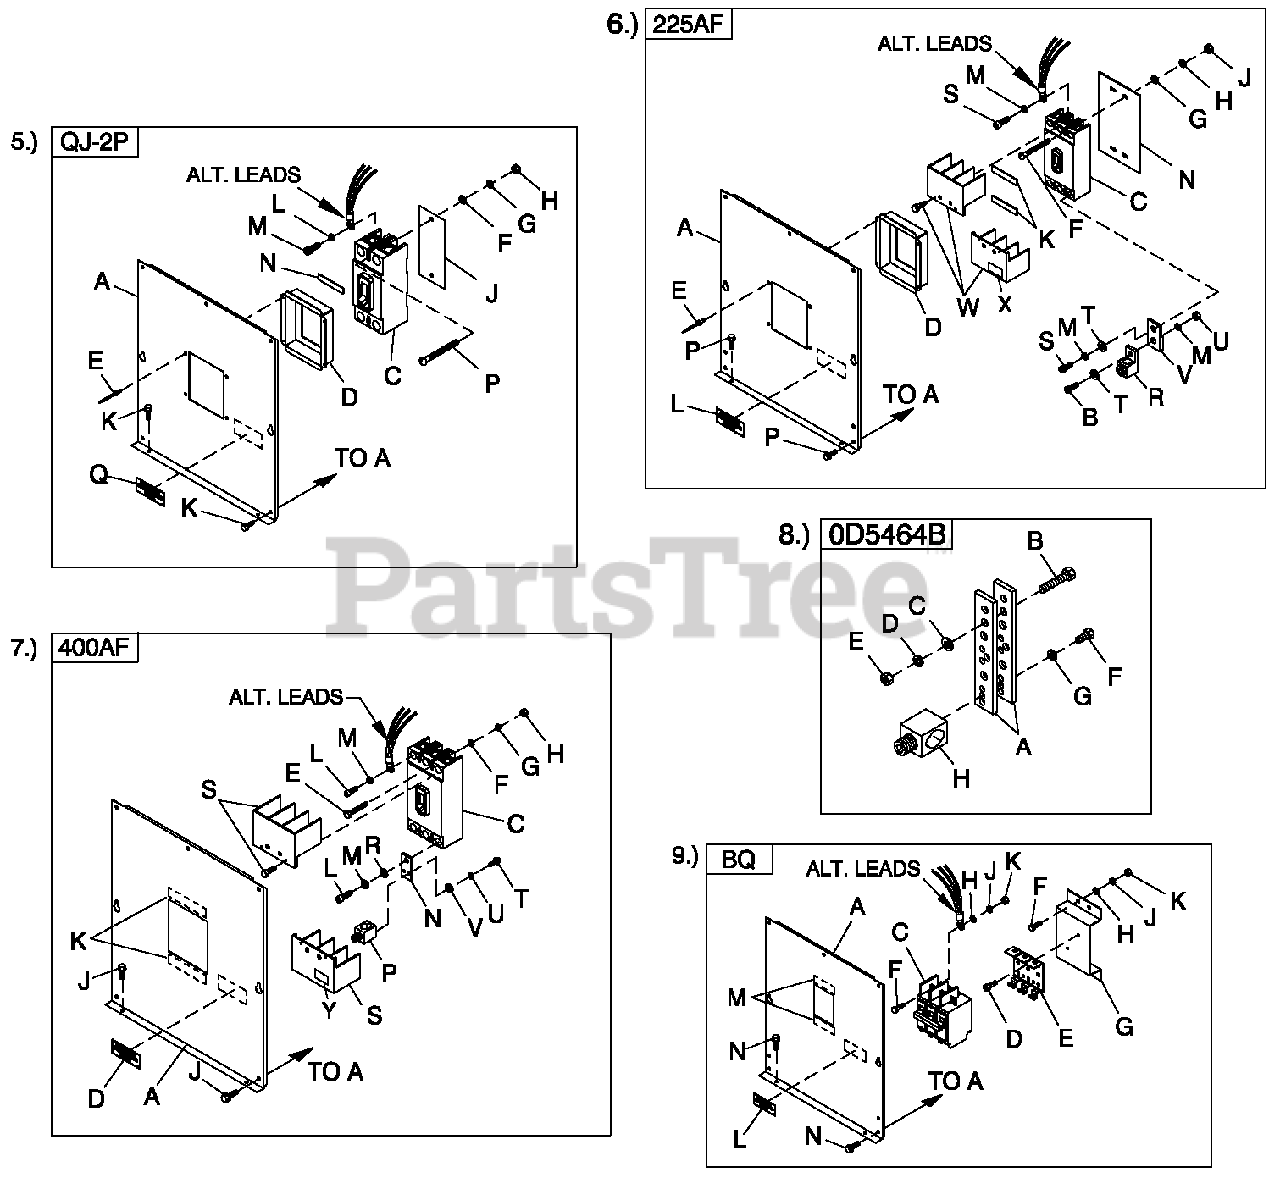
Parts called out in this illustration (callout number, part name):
9	UL CIRCUIT BR EAKER (BQ)
A	COVER QJ 2P F R M C B
C	CB 0225A 240V 2P S QJ22
D	COVER QJ 2P CB DISH
E	RIVET POP .125 X .275 SS
F	WASHER FLAT 1/4-M6 ZINC
G	WASHER R LOC K M6-1/4
H	NUT HEX 1/4-20 STEEL
J	INSUL CB 2 P Q J
K	SCREW THF M6-1 X 16 N WA Z /J S
L	W A S H E R LOC K 3/8
M	SCREW SHC 3/8-16 X 3/4 G8.8 NZ
N	TAPE ELEC 1/2 FOAM (AS REQ' D)
P	SCREW RHM 1 /4 -2 0 X 3
Q	DEC AL CUSTOMER CONNECT INSIDE
A	COVER CB C2-C4 (225AF)
B	SCREW SHC M8-1.25 X 25 G12.9
C	CIRCUIT BREAKERS 200A FRAME (3P)
D	COVER CB DISH 225AF (3P)
F	SCREW RHM # 8 -3 2 X 3 -1 /4
G	WASHER FLAT #8 ZINC
H	WASHER LOC K #8-M4
J	NUT HEX #8-32 S TEEL
K	TAPE ELEC 1/2 FOAM
L	DEC AL CUSTOMER CONNECT INSIDE
M	WASHER LOC K M8-5/16
N	INSULATOR CB 22 5 A F (3P )
P	SCREW THF M6-1 X 16 N W A Z /J S
R	LUG SLD LSS 300 MCM-6 AL/CU
S	SCREW SHC M 8-1.25X 2 0 G 8
T	W A S H E R F L A T 5/16-M 8ZIN C
U	NUT HEX M8-1.25 G8 C LE AR ZINC
V	BUS BAR 200A LUG AD APTO R
W	TERMINAL COVER CB
X	DECALTERMINAL SHOCK HZD BI
A	COVER CB C2-C4 400AF
C	CIRCUIT BREAKERS 400A FRAME
D	DECAL CUSTOMER CONNECT INSIDE
E	SCREW RHM 1 0 -3 2 X 4
F	WASHER FLAT #10 ZINC
G	WASHER LOC K #10
H	NUT HEX #10-32 STEEL
J	SCREW THF M6-1 X 16 N W A Z /J S
L	SCREW SHC M 1 0 -1 .5 X 2 5 G 1 2 .9
M	W A S H E R LOC K M10
N	BUS BAR CB AD A PTE R 225-400 A
P	LUG SLD LSS 600/250-1/0 X 1/4-28
S	TERM COVER CB
T	SCREW HHC 1/4-28 X 1/2 G5
U	WASH ER LOCK M6-1/4
V	WASHER FLAT 1/4-M6 ZINC
W	SCREW SHC M10 -1 .5 X 2 5 G 1 2 .9
X	WASHER LOCK M10
Y	DEC AL TE R M IN A LS H O C K HZD BI
A	BUS BAR NEUTRAL BLO C K 390
B	SCREW HHC M8-1.25 X 45 G8.8 FT
C	WASH ER FLAT 5/16-M8 ZINC
D	W SH ER LOCK M8-5/16
E	NUT HEX M 8 -1 .2 5 G 8 Y E L CHR
F	SCREW HHC 1/4-28 X 3/4 G5
G	W ASH ER LOCK 1/4-M 6SS
H	LUG SLD LSS 600/250-1/0 X 1/4-28
A	COVER BQ CIR BR EAKER C PL 3P
C	CB 0125 A 2P 240V S B Q 2 LL
D	SCREW PHTTM 4 -0 .7 X 10 ZYC
E	BRKT CB MTG BAC K
F	SCREW RHM # 1 0 -3 2 X 3 /4
G	BRKT B Q C B STANDOFF
H	W ASH ER FLAT #10 ZINC
J	W ASH ER LOCK #10
K	NUT HEX #10-32 STEEL
L	DECAL CUSTOMER CONNECT INSIDE
M	TAPE ELEC 1/2 FOAM
N	SCREW THF M6-1 X 16 N WA Z/JS
